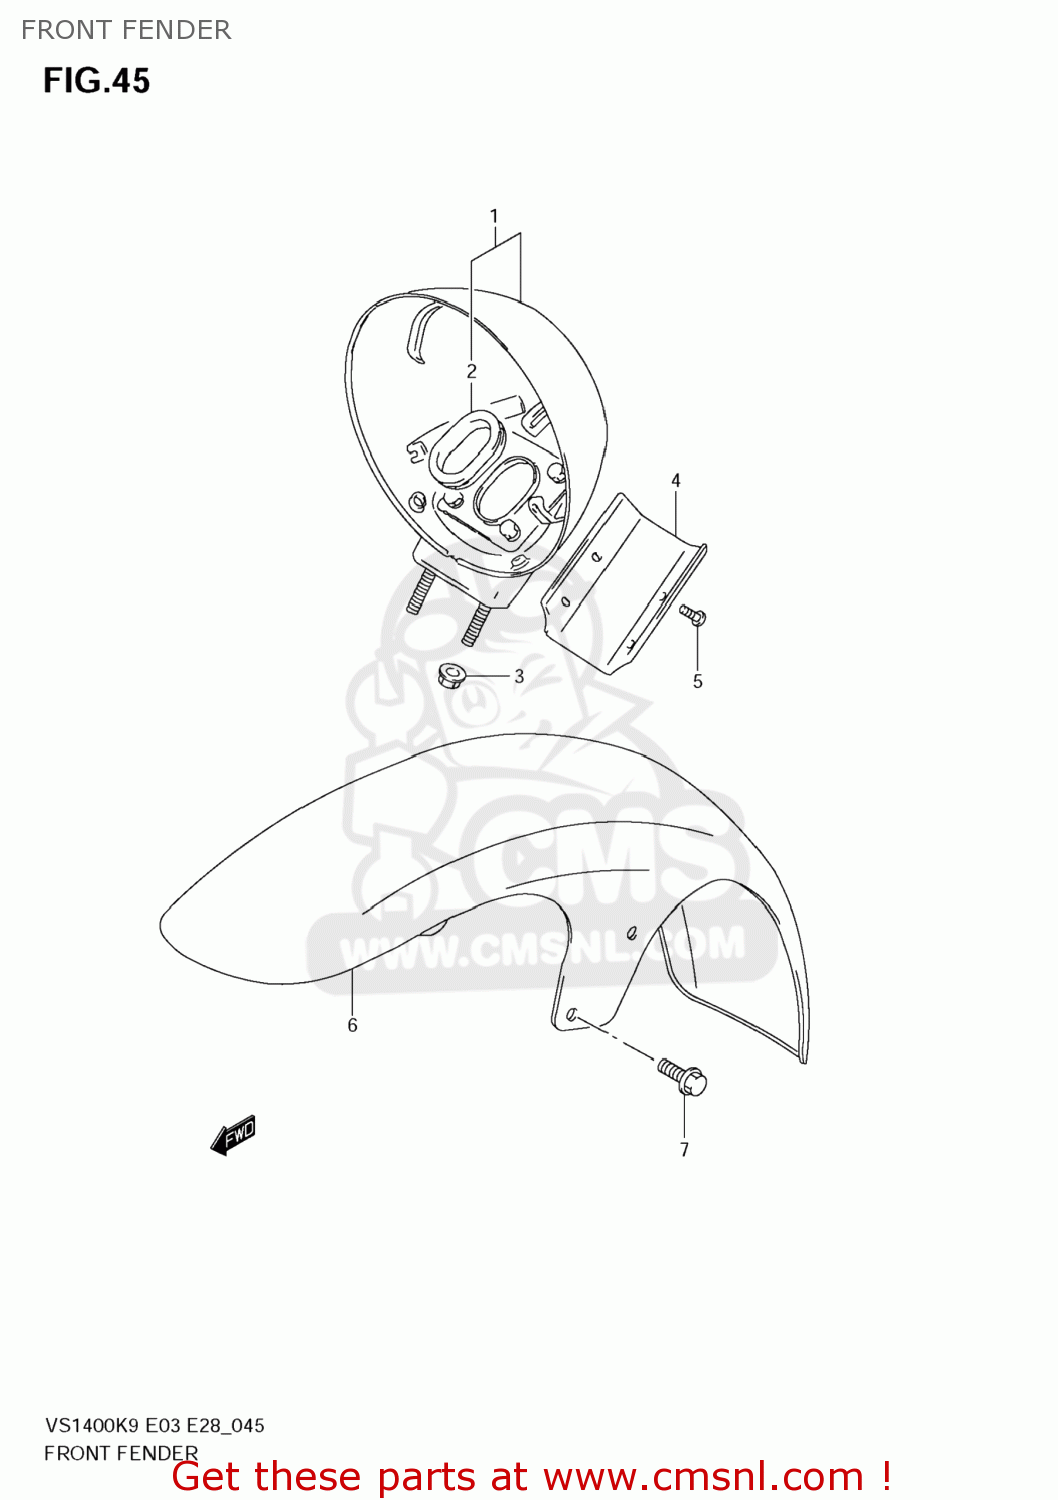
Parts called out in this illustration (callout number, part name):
1	HOUSING,HEADLAMP
2	GROMMET
3	NUT
4	COVER,HEADLAMP HSG
5	SCREW
6	FENDER,FR
7	BOLT
